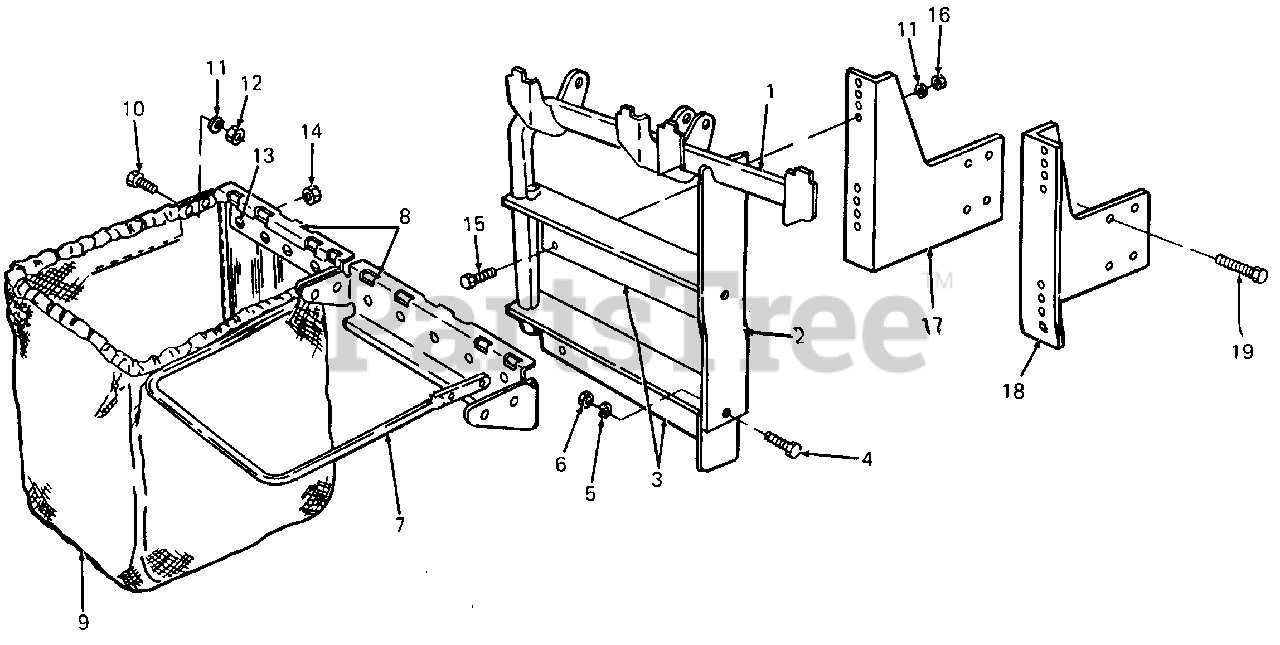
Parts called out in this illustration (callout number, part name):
1	Tube Assy, Catcher Support
2	Bracket, Support
3	Bracket, Support Tube Mounting
4	Screw, Hex, 5/16-18 X .75 Lg
5	Washer, Lock, 5/16
6	Nut, Hex, 5/16-18
9	Bag, Grass Catcher
10	Screw, Hex, 1/4-28 X .75 Lg
11	Washer, Lock, 1/4
12	Nut, Hex, 1/4-28
13	Screw, Truss Mach, #10-24 X .38 Lg
14	Nut, Hex Sems, #10-24
15	Screw, Hex, 1/4-20 X .62 Lg GR 5
16	Nut, Hex, 1/4-20 GR 5
17	Bracket, LH Bagger Support
18	Bracket, RH Bagger Support
19	Screw, Hex Cap, 3/8-16 X 1.0 Lg GR5
